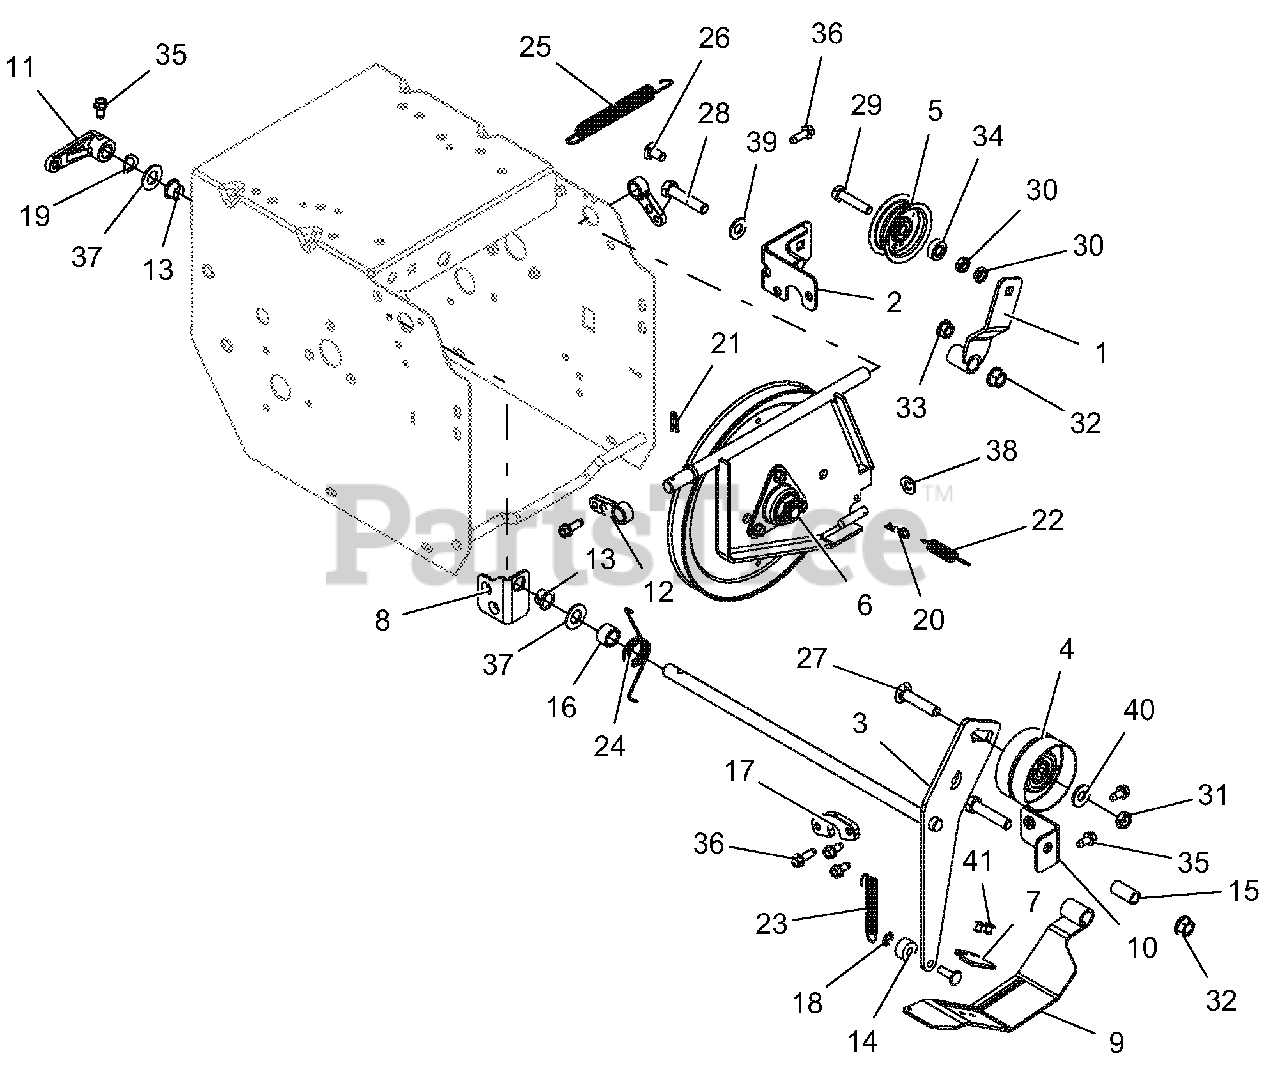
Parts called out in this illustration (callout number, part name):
1	ARM, TRACTION IDLER
2	WELDMENT, FRAME BRACKET
3	WELDMENT, ATTACHMENT IDLER ARM
4	IDLER, FLAT-2.75 OD X .375 ID
5	KIT, FLAT IDLER
6	PLATE, SWING - ASSEMBLY
7	PAD, BRAKE
8	BRACKET, MOUNT - IDLER ARM
9	BRAKE ARM W/PAD
10	BRACKET, BRAKE MOUNT
11	ARM, CLUTCH - ATTACHMENT
12	SUPPORT BUSHING, SWING GATE
13	BUSHING, POLYLINER-.50 SPLIT
14	BSHG,SLV .265 X .625 X .375
15	BSHG-SLV .385X.500X1.045
16	BSHG-SLV .510X.751X.475
17	SPACER, SWING GATE
18	RG-RTNG-EXT .250X.010
19	WSHR-WAVE .50X.75X.015 .13FRHT
20	PIN-HAIR INT .08X.18X1.18 YWZC
21	CLIP, SPRING
22	SPRING, EXT. .043X.438X1.64
23	SPRING-EXT .047 X .438 X 1.85
24	SG-TORS .075 X .955
25	SPRING, SWIVEL HOOK EXTENSION
26	@BLT-RHDSSQNK .31-18X.62 G5YZ
27	@BLT-RHDSSQNK .38-16X1.75 G5YZ
28	@BLT-HEX .38-16X1.75 GR5 YWZC
29	@BLT-HEX .31-18X1.50 GR5 YWZC
30	@NUT-LK-CTR-JAM .31-18 YWZC
31	@NUT-LK-CTR-JAM .375-16 YWZC
32	@NUT-LK-TOP-FLG .38-16 YWZC
33	@NUT-LK-TOP-FLG .31-18 YWZC
34	SPCR, BRG .315X.500X.358X.281
35	SCR-TAP .25-20X.50 HWH TR YWZ
36	SCR-TAP-PM .25-20X.75 TR YWZ
37	WSHR-FL-STL.531X1.00X.063 YWZC
38	@WSHR-FL-STL.344X.688X.065YWZC
39	@WSHR-FL-STL.406X.812X.065 YWZ
40	@WSHR-FL-STL.38X.875X.083 YWZC
41	RVT-POP .187 YZ
